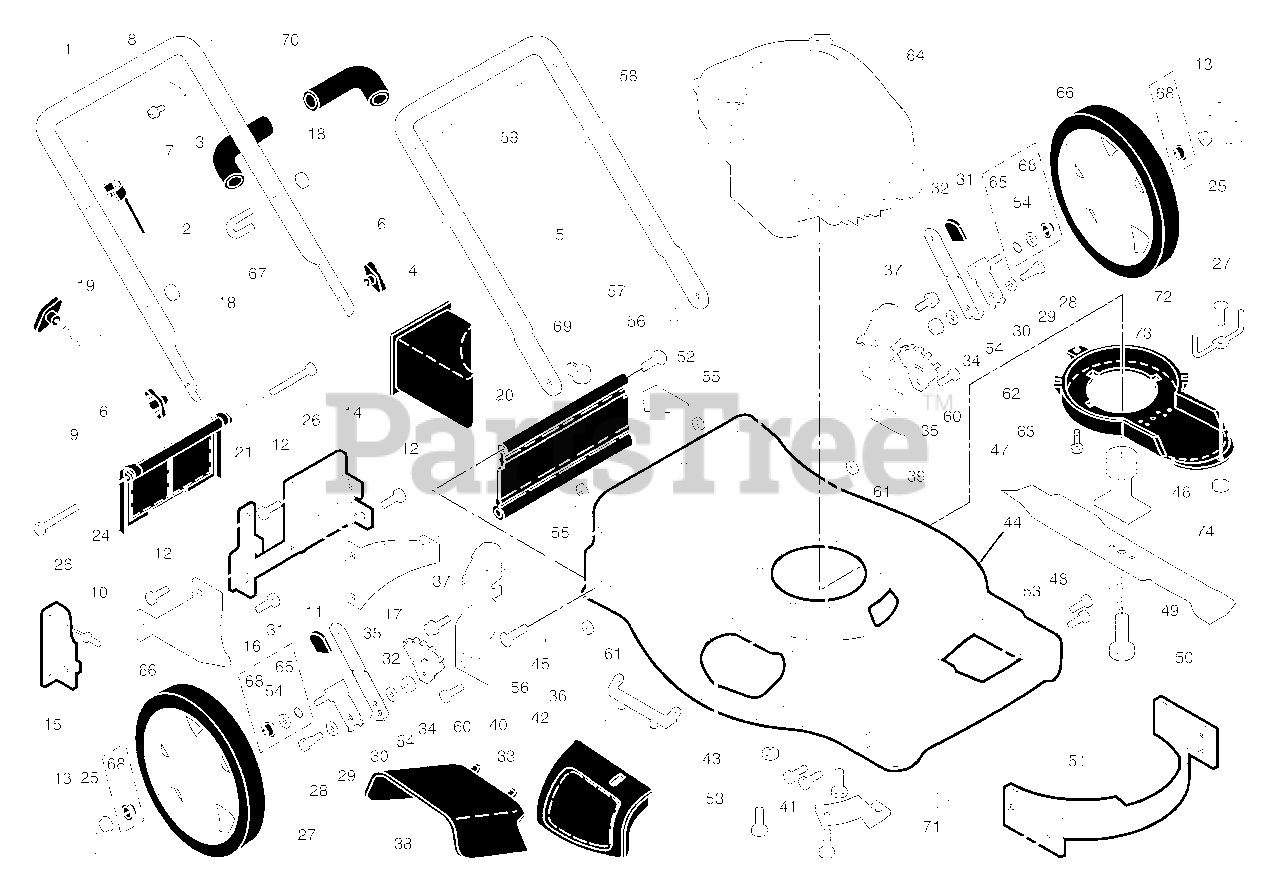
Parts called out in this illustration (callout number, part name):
1	Upper Handle
2	Engine Zone Control Cable
3	Bracket, Upstop
4	Mulcher Plug
5	Wire Tie
6	Handle Knob
7	Screw
8	Control Bar
9	Rear Door Assembly
10	Pop Rivet
11	Screw, Self Tapping #10-24 x 5/8
12	Screw, Hex Hex Head, Sems 1/4-20 x 1/2
14	Back Plate
15	Side Baffle
16	Discharge Baffle
17	Rear Baffle
18	Keps Locknut 1/4-20
19	Rope Guide
20	Rear Skirt
21	Spring, Rear Door, LH
24	Spring, Rear Door, RH
25	Nut, Hex, Flanged
26	Bolt, Rear Door
27	Wheel, Rear
28	Bolt, Shoulder 3/8-16 x 1
29	Washer, Belleville
30	Axle Arm Assembly
31	Selector Knob
32	Selector Spring
33	Mulcher Door
35	Wheel Adjusting Bracket
36	Hinge Bracket Assembly
37	Screw, Sems, Thread Cutting 5/16-18 x 3/4
38	Discharge Deflector
39	Handle Bracket Assembly, LH
40	Handle Bracket Assembly, RH
41	Bolt, Hex Head, Engine 3/8-16
42	Spring, Torsion
43	Nut, Hex, Nylock
44	Kit, Lawn Mower Housing
45	Rod, Hinge
46	Blade Adapter / Pulley
47	Blade, 22"
48	Washer, Hardened
49	Washer, Helical
50	Screw, Machine, Hex Head 3/8-24 x 1-3/8 Grade 8
51	Front Baffle
52	Danger Decal
53	Screw
54	Washer, Flat
55	Nut, Hex 3/816
56	Screw, Hinge 1/4-20 x 11/4
57	Hairpin Cotter
58	Lower Handle
59	Handle Bolt
60	Bolt, Hex Head
62	Debris Shield
63	Screw, Debris Shield
66	Kit, Bushing, High Wheel
67	Clip, Packaging
68	Bushing, Nylon, Black
69	Clip, Cable
70	Foam Grip
71	Mounting Bracket, Debris Shield
72	Screw #8
73	Belt Keeper
74	Nut, Hex
